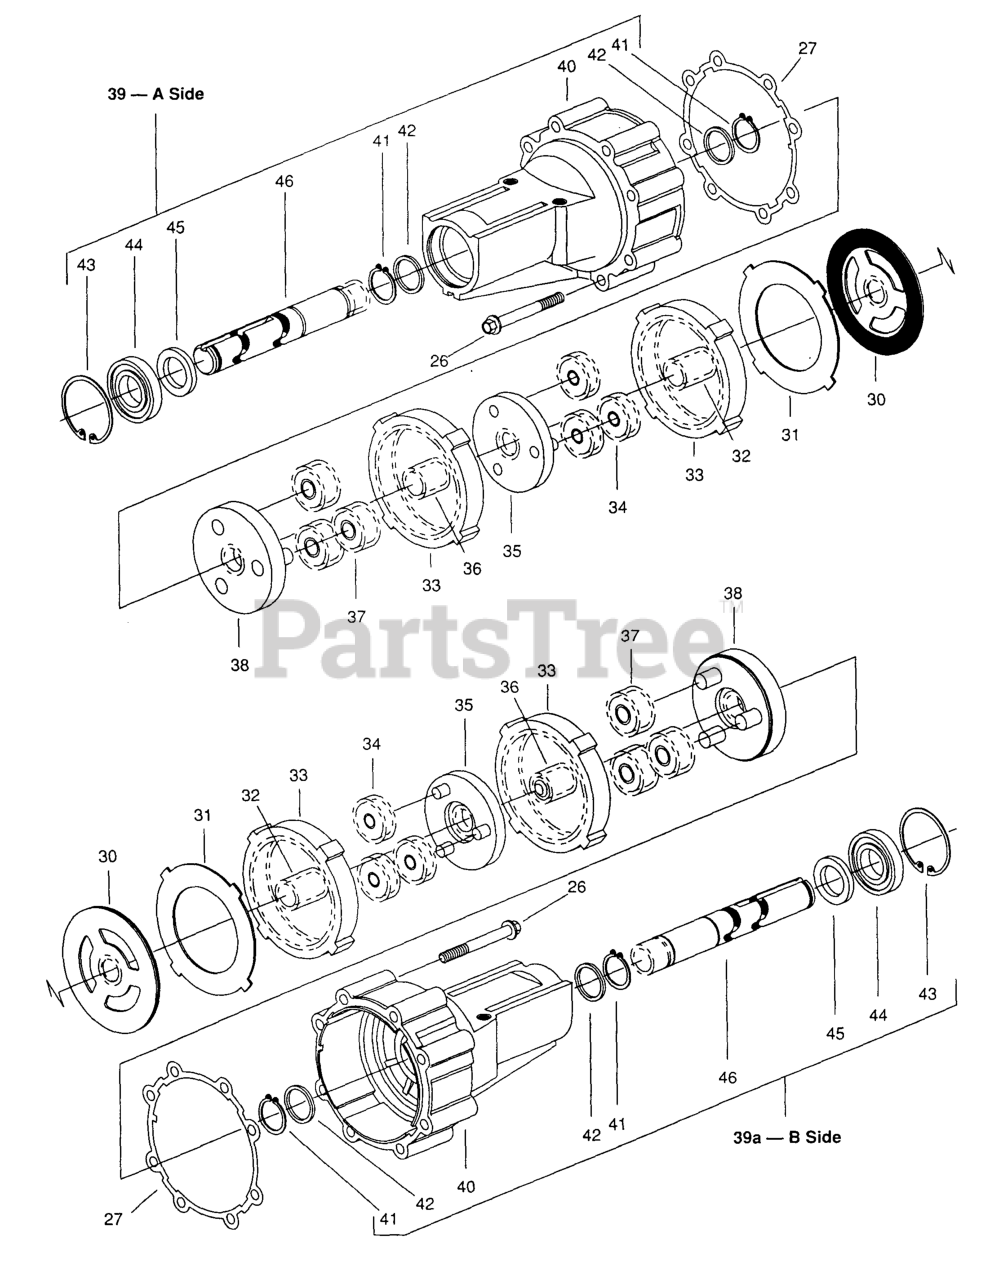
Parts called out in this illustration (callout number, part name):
28	MOTOR ROTOR BALL
31	BACKUP PLATE
33	RING GEAR 57T
35	PRIMARY CARRIER 15T
38	SECONDARY CARRIER SA
39	Tapered Axle Kit, LH B
39A	Tapered Axle Kit, LH B
41	External Retaining Ring
42	THRUST WASHER
43	Internal Retaining Ring
